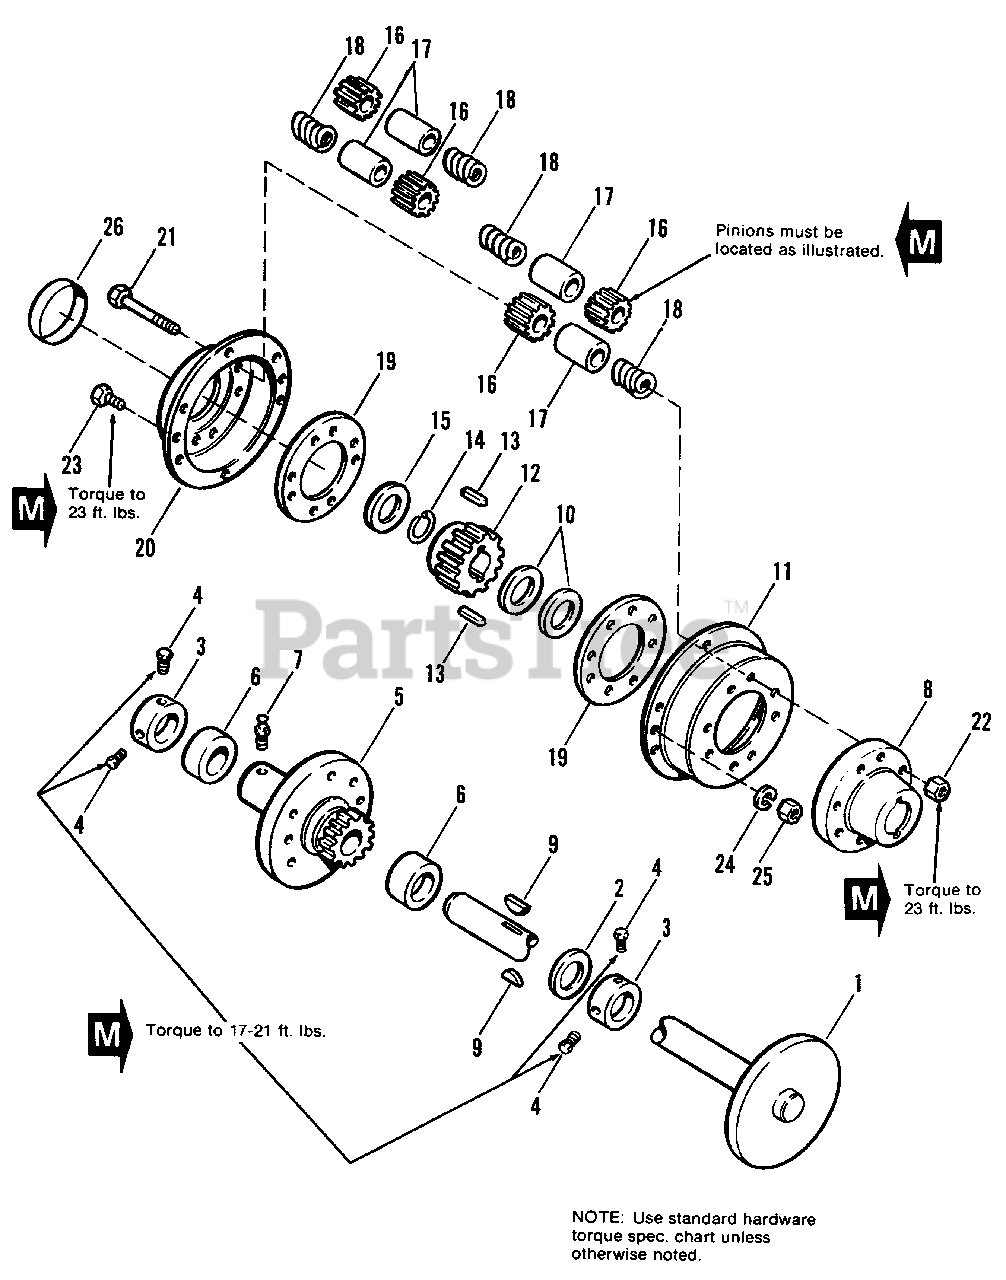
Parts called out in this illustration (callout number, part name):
1	REAR AXLE ASSY.
3	COLLAR, Set
4	SETSCREW, Sq. Hd., 5/16-18 x 1/2
5	R.H. WHEEL HUB ASSY.
7	FITTING, Grease
8	CARRIER, Diff.
10	WASHER, Axle
11	COVER, Diff.
12	GEAR, Diff.
13	KEY, Hi Pro, 1/4 x 3/4
14	RING, Retaining
15	WASHER, Axle
16	PINION, Diff.
17	SPINDLE, Diff. Pinion
19	RING, Spacer
20	COVER, Diff.
21	CAPSCREW, Hex Hd., 3/8-16 x 2-1 /2
22	NUT, Hex, 3/8-16
23	CAPSCREW, Hex, 1/4-20 x 5/8
24	LOCKWASHER, 1/4
25	NUT, Hex, 1/4-14
26	SEAL, Cover
27	DIFFERENTIAL SUBASSY. (Includes Ref. No's. 8, 11, 16 thru 26)
